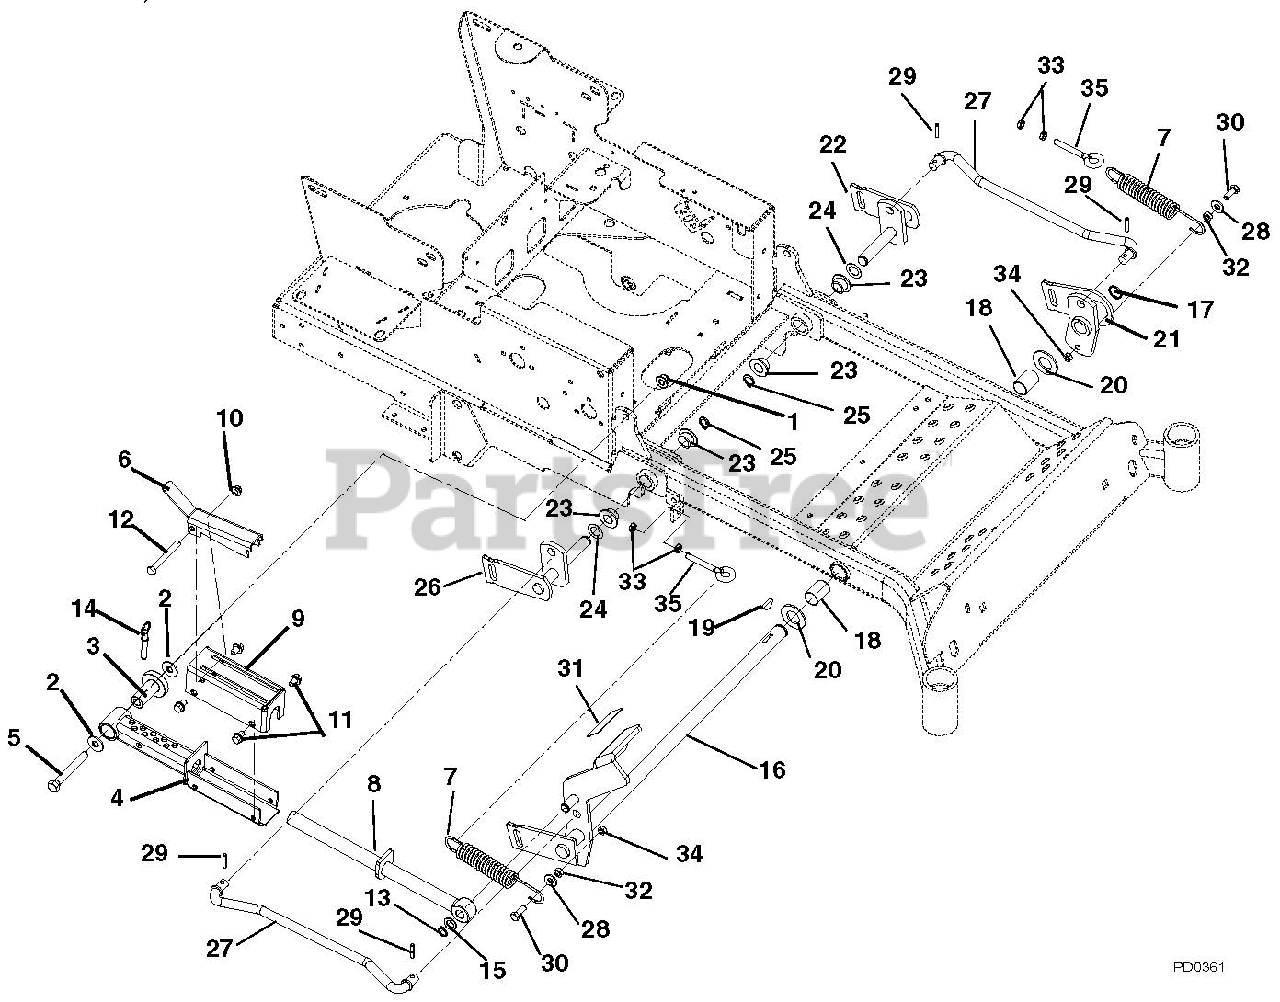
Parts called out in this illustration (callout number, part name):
1	@NUT-LK-NYL-FLG .50-13 YWZC
2	WSHR-FL-STL .531X1.250X.10 YWZ
3	BEARING, PEDESTAL
4	WMT, MECHANICAL LIFT
5	@BLT-HEX .50-13X3.75 GR5 YWZC
6	LOCK-UP, MECH LIFT
7	SG-TENS .162X1.25X8.25 WLD 25
8	WMT, MECH. LIFT SHAFT (.62)
9	WMT, MECH LIFT COVER
10	@NUT-LK-NYL-FLG .38-16 YWZC
11	@SCR-TAP .38-16X.50 HWH TR YWZ
12	@BLT-HEX .38-16X3.25 GR5 YWZC
13	RG-RTNG-EXT .625X.050
14	PIN, SPRING BALL .375OD X 1.50
15	WSHR-FL-STL .630X1.005X.062 YZ
16	WMT, FOOT OPERATED DECK LIFT
17	RG-RTNG-EXT 1.00X.078
18	BSHG,1.00ID X 1.125OD X 1.50LG
19	KEY-WDRF .25X1.00 HRD #15
20	WSHR-FL-STL- 1.062X2.0X.134 YZ
21	WMT, LH FRONT MOWER LIFT
22	WMT, LH REAR LIFT ARM (100)
23	BSHG-FLG .762X1.0X.580X1.48 NY
24	WSHR-HDND-THRST .758X1.23X.031
25	RG-RTNG-EXT .689X.078
26	WMT, RH REAR LIFT ARM (100)
27	ROD, LIFT ASSIST 16.35"
28	@WSHR-FL-STL.438X1.00X.083 YWZ
29	PIN-ROLL .250X1.25 STNLESS STL
30	@BLT-HEX .38-16X1.00 GR5 YWZC
31	GRIP, PEDAL 1.50 X 3.00
32	BSHG-SLV .377X.624X.235
33	NUT-HEX-JAM .375-16 YWZC
34	@NUT-LK-CTR-JAM .375-16 YWZC
35	BLT-EYE .375-16X2.50 YWZC
